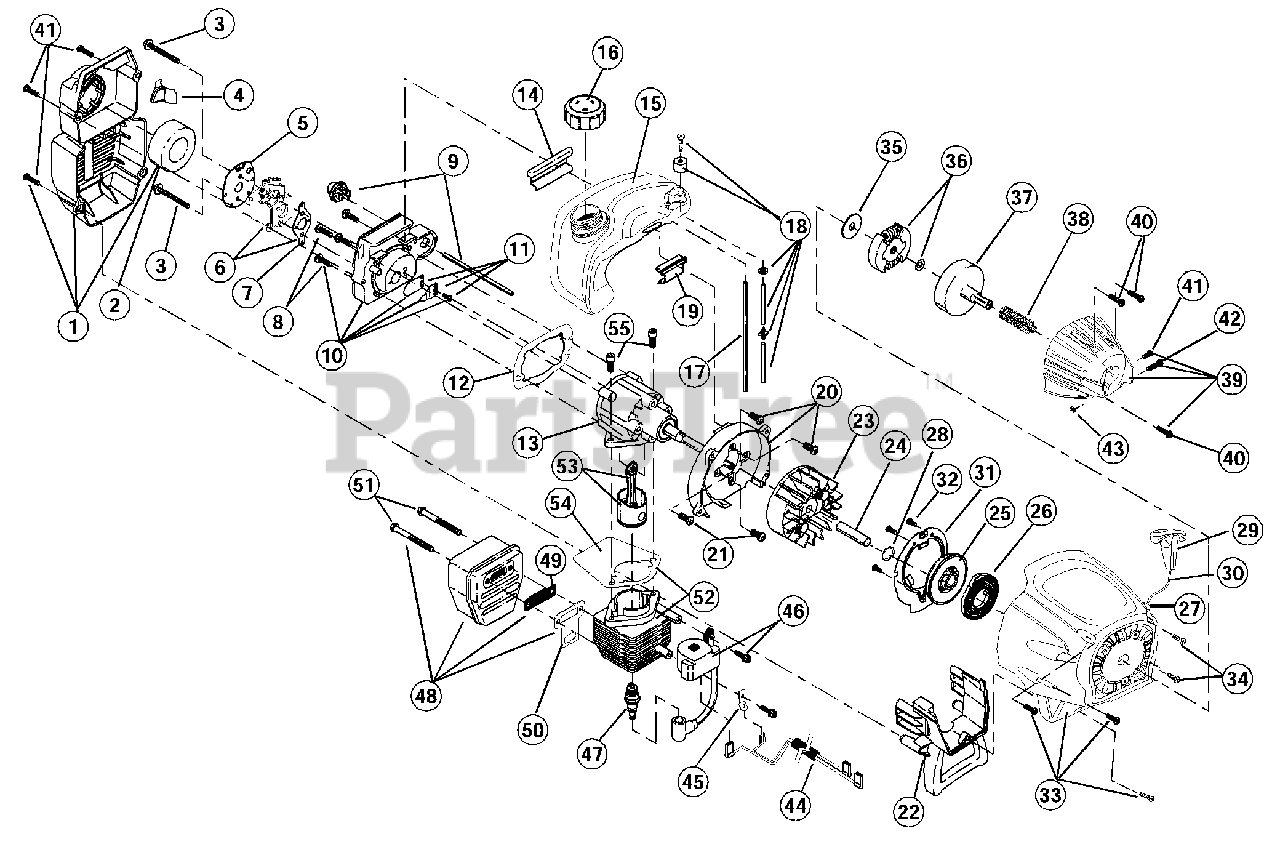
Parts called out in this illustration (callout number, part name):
1	Air Cleaner/Muffler Cover Assembly
2	Air Cleaner Filter
3	Carburetor Mounting Screw Assembly
4	Choke Extension
5	Choke Plate
6	Carburetor Assembly W/Limiter Caps
7	Carburetor Gasket
8	Carb Mount Screw
9	Primer and Hose Assembly
10	Carb Mount Assembly
11	Reed Assembly
12	Carburetor Mount Gasket
13	Crank Case Service Assembly
14	Rear Mounting Pad
15	Fuel Tank Assembly
16	Fuel Cap Assembly
17	Fuel Return Line
18	Fuel Line Assembly
19	Front Mounting Pad
20	Shroud Assembly
21	Shroud Screw
22	Shroud Extension and Stand
23	Flywheel Assembly
25	Recoil Pulley Assembly
26	Recoil Spring
27	Rope Guide
28	Pulley Retainer
29	Pull Handle
31	Pressure Plate Assembly
32	Plate Screw
33	Starter Housing Assembly
34	Housing Screw
35	Clutch Washer
36	Clutch Rotor Assembly
37	Clutch Drum Assembly
39	Clutch Cover Assembly
40	Cover Screw
41	Anti-Rotation Screw
42	Clamping Screw
43	Clamping Nut
44	Wire Leads and Sleeve
45	Ground Tab
46	Module Assembly
48	Muffler Assembly
49	Spark Arrestor Screen
50	Exhaust Gasket
51	Muffler Mounting Bolt Assembly
52	Cylinder Assembly
53	Piston and Rod Assembly
54	Cylinder Gasket
55	Cylinder Bolt
